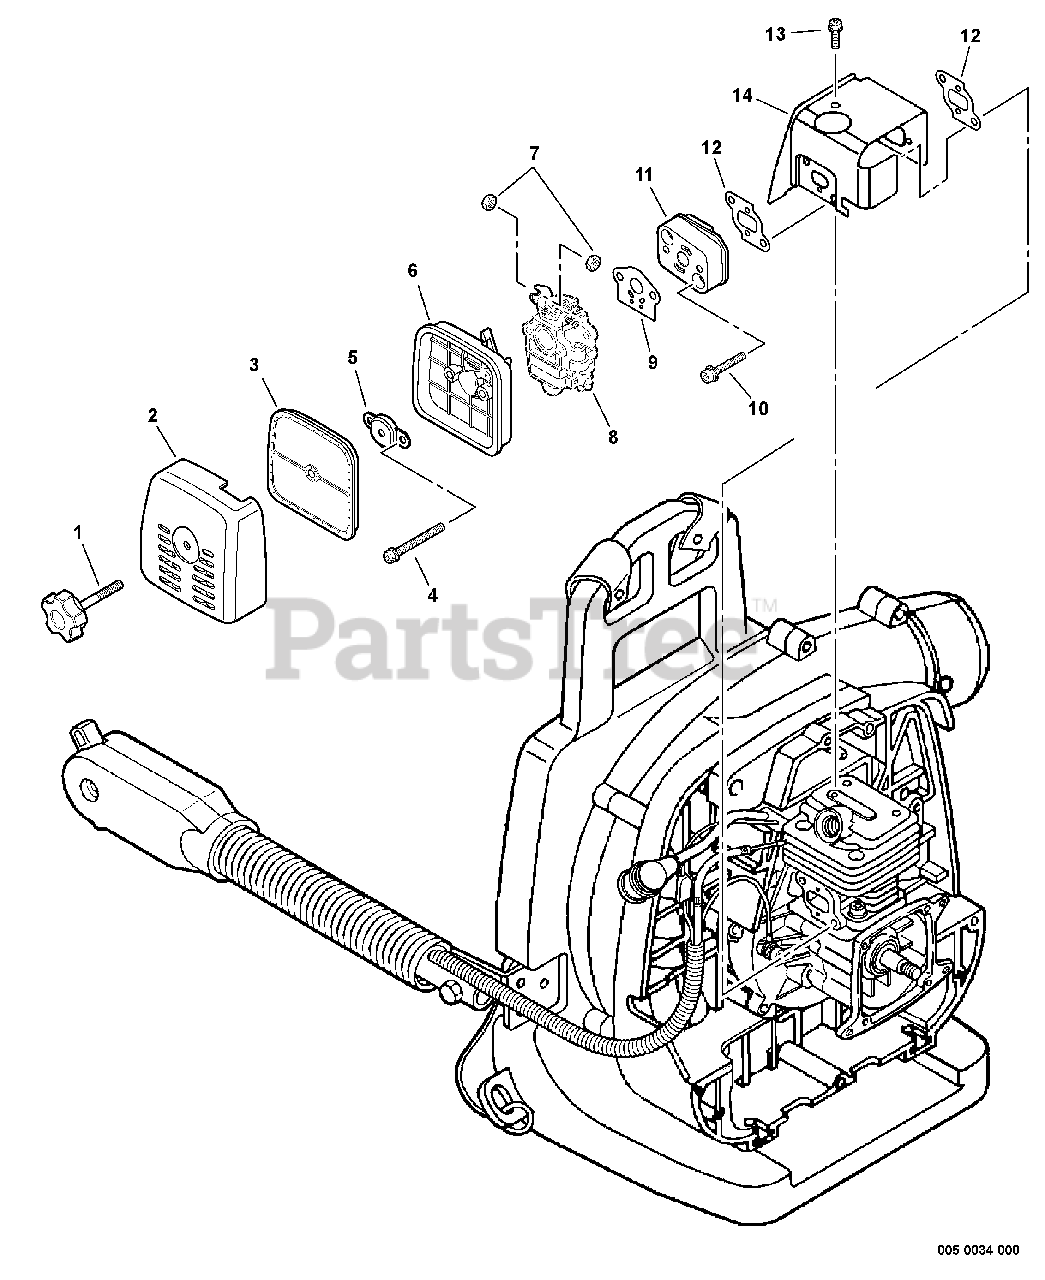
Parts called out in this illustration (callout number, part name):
1	THUMBSCREW
2	COVER, AIR FILTER
3	FILTER, AIR - HEAVY DUTY
4	PLATE, PREVENT
5	SCREW - 5X60
6	CASE, AIR FILTER
8	CARBURETOR
9	GASKET, INTAKE
10	INSULATOR, INTAKE
11	SCREW - 5X25
12	GASKET, INTAKE
13	SHIELD, CYLINDER
14	SCREW - 5X10
